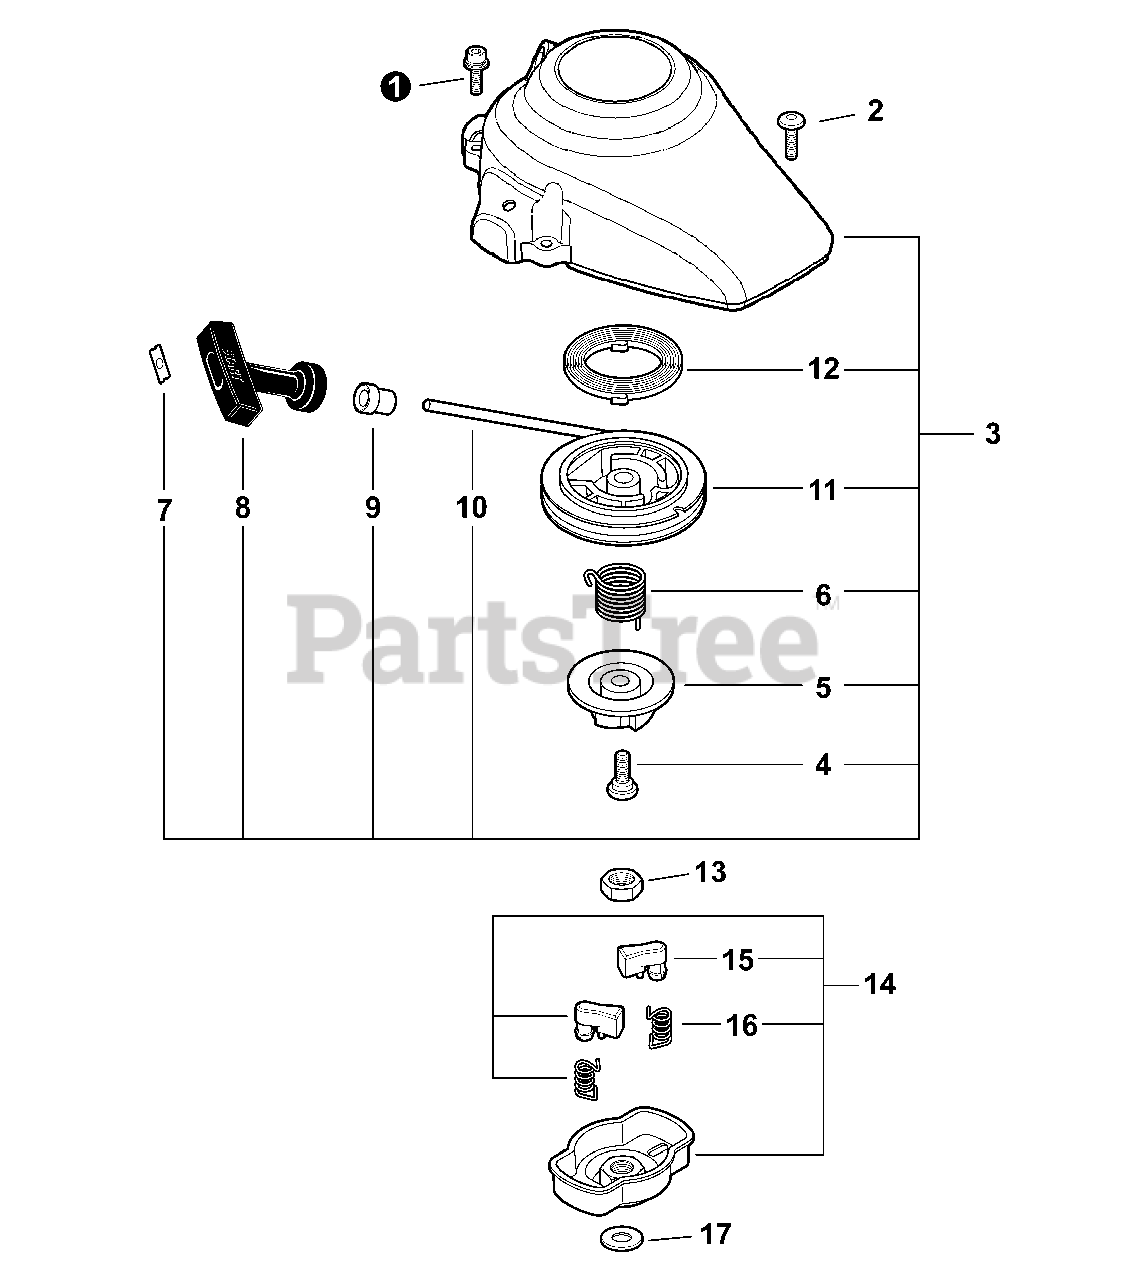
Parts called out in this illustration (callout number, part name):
1	SCREW - 4×16
2	SCREW - 4
3	STARTER ASSY
4	SCREW
5	CATCHER, PAWL
7	RETAINER, ROPE
8	GRIP, STARTER
9	GUIDE, ROPE
10	ROPE, STARTER - 3×700
11	REEL, ROPE
12	SPRING, REWIND
13	NUT - LEFT HAND
14	STARTER PAWL ASSY
15	PAWL, STARTER
16	SPRING, RETURN
17	WASHER - 8
